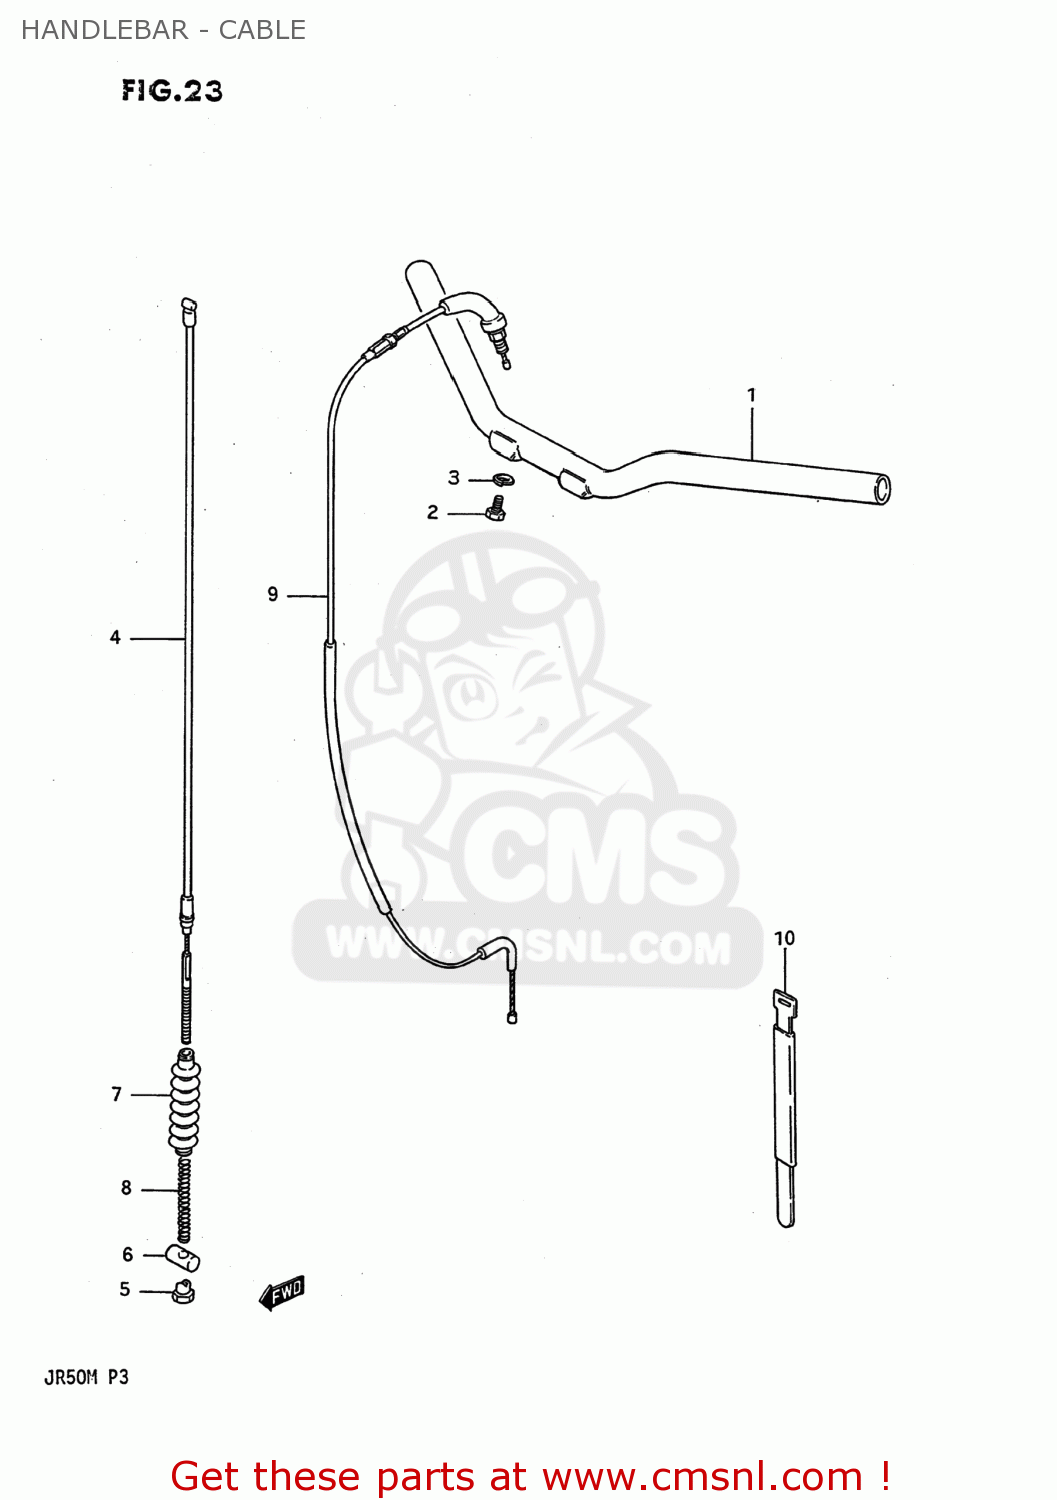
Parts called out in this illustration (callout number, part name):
1	HANDLEBAR
2	BOLT,8X16
3	LOCK WASHER
4	CABLE ASSEMBLY,FRONT BRAKE
5	NUT
6	PIN,10X19
7	SEAL,DUST(7X16X75)
8	SPRING
9	CABLE ASSEMBLY,THROTTLE
10	CLAMP
